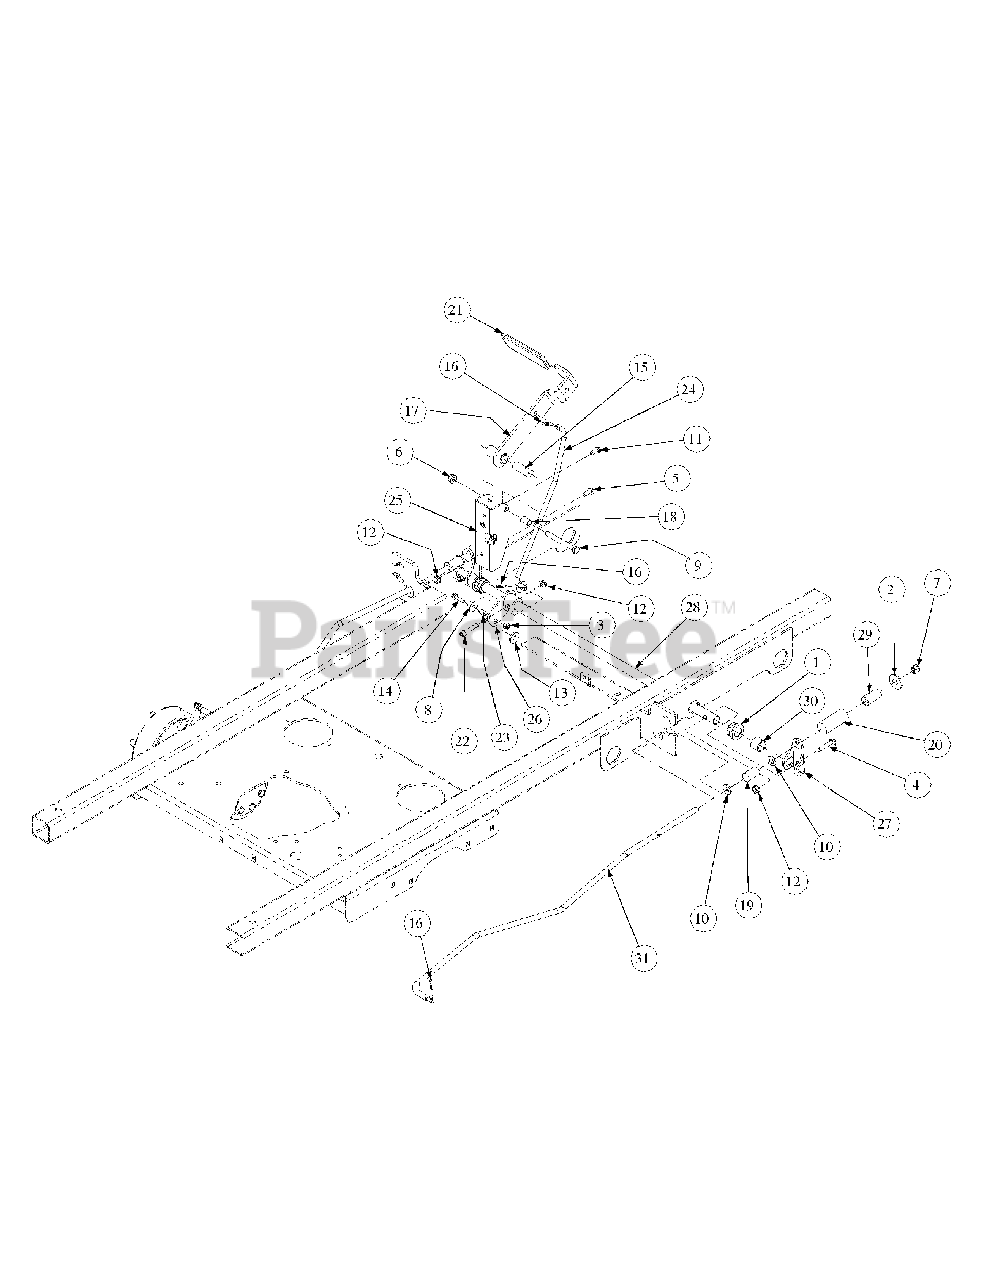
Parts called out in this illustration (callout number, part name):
1	Hex Flange Bearing, .752 ID
2	Washer, 1/2
3	Lock Nut, Nylon Insert, 1/4-20
4	Hex Cap Screw, 5/16-18 x 1-1/2
5	Hex Cap Screw, 5/16-18 x 1.0
6	Flange Lock Hex Nut, 3/8-16
7	Nut, 7/16-14, Nylock
8	Spacer, Control Rod
9	Hex Cap Screw, 3/8-16 x 3-1/4
10	Flat Washer, .469 ID, .875 OD, .105
11	Screw, TT, 1/4-20, 0.75, Hex Index Washer
12	Nut, Lock, Hex Flange, 5/16-18
13	Flat Washer, .406 ID x 1.0 OD x .105
14	Screw, TT, 1/4-20, 1.0, Hex Index Washer
15	Spacer, .39 x .63 x 1.75
16	Cotter Pin, .072 x 1.12 Lg
17	Brake Handle
18	Spacer, .375 x .50 x .75 Lg
19	Neutral Brake Spring
20	Force Brake Spring
21	Parking Brake Grip
22	Socket Head Capscrew, 5/16-18 x 1.50
23	Spacer, Pump Release
24	Brake Rod
25	Parking Brake Mounting Bracket
26	Brake Arm Assembly
27	Brake Arm Bracket
28	Pivot Brake Shaft
29	Hose, .5 ID x .78 OD, Low Pressure
30	Spacer, .76 ID x 1.0 OD x 3/4
31	Connector Rod Rod
